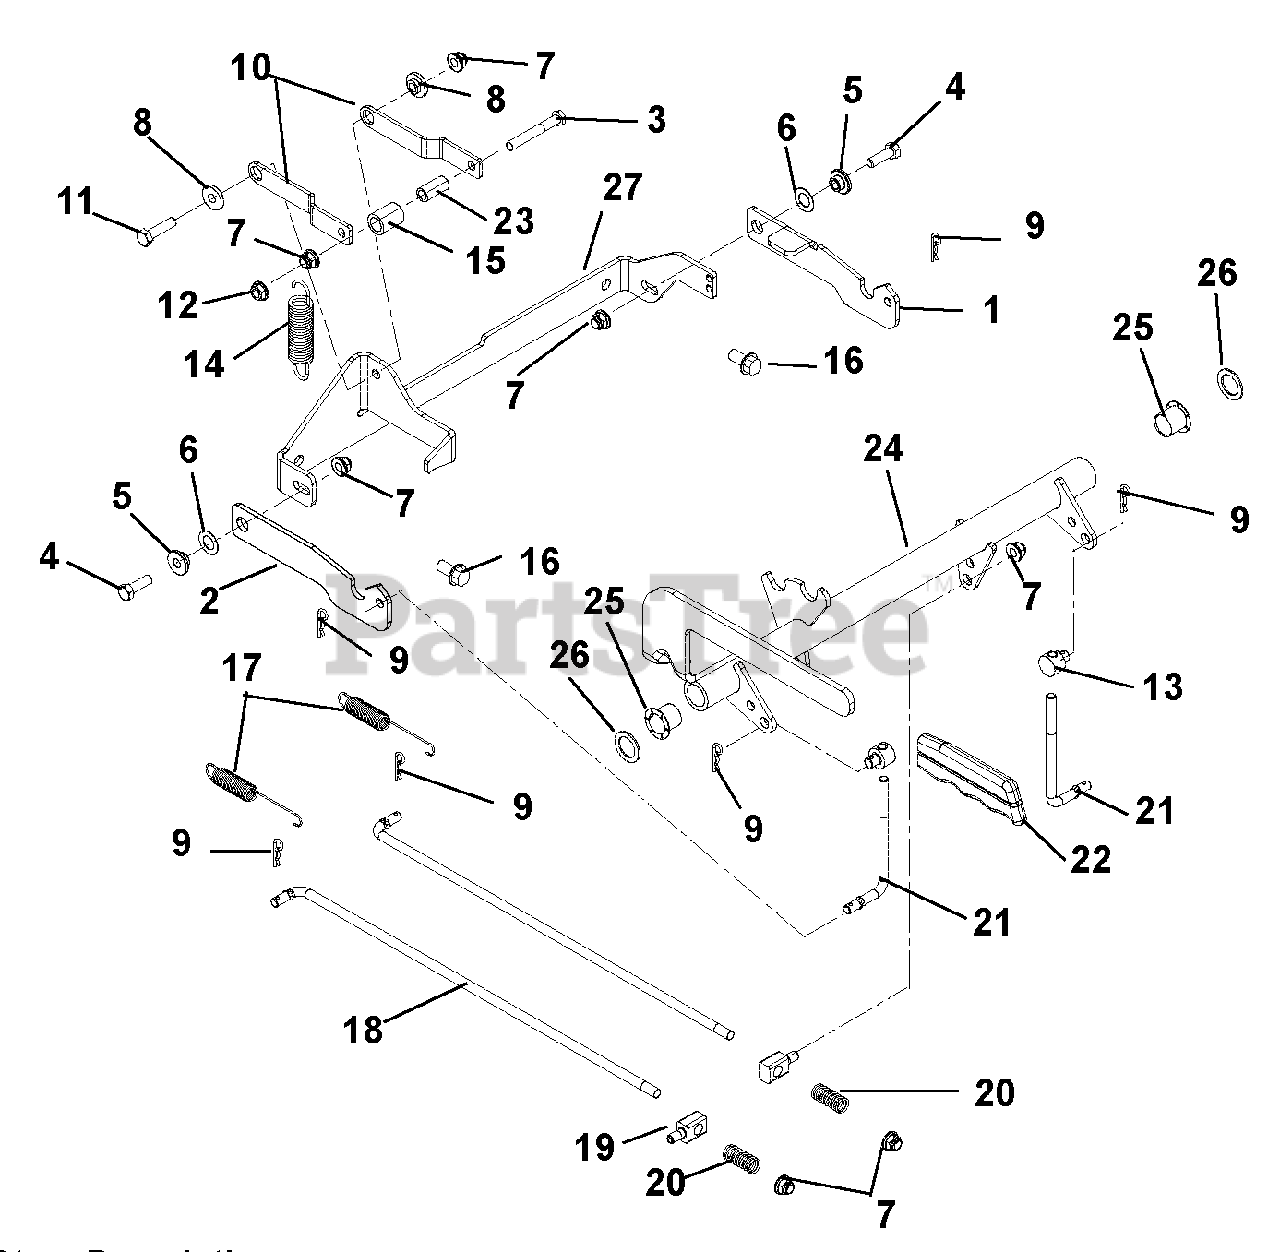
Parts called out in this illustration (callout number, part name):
1	LINK, BRAKE INTERLOCK
2	INTERLOCK, BRAKE
3	@BLT-HEX .31-18X2.25 GR5 YWZC
4	@BLT-HEX .31-18X1.00 GR5 YWZC
5	BSHG-FLG .32X.500X.344X.880
6	WSHR-FL-STL .505X.875X.024 YWZ
7	@NUT-LK-NYL-FLG .31-18 YWZC
8	BSHG, FLG .325X.499X.26X.88
9	PIN-HAIR INT .08X.18X1.18 YWZC
10	ARM, BRAKE CAM
11	@BLT-HEX .31-18X1.25 GR5 YWZC
12	@NUT-LK-TOP-FLG .31-18 YWZC
13	TRUNNION, BRAKE .31-18 UNC
14	SG-TENS .105X.812X3.88 WLD 15
15	ROLLER, CAM LOCK
16	@SCR-TAP .38-16X.75 HWH TR YWZ
17	SG-TENS .056X.60X4.40
18	ROD, PARK BRAKE
19	PIN, PIVOT/TRUNNION
20	SPRING, COMPRESSION
21	LINK, INTERLOCK BRAKE
22	GRIP, PARKING BRAKE (YELLOW)
23	BSHG, SPCR .330X.500X1.01 PM
24	SHAFT, BRAKE
25	BUSHING, IGLIDE CLIP
26	WSHR-FL-STL.754X1.125X.062YWZC
27	BRKT, BRAKE MTG
